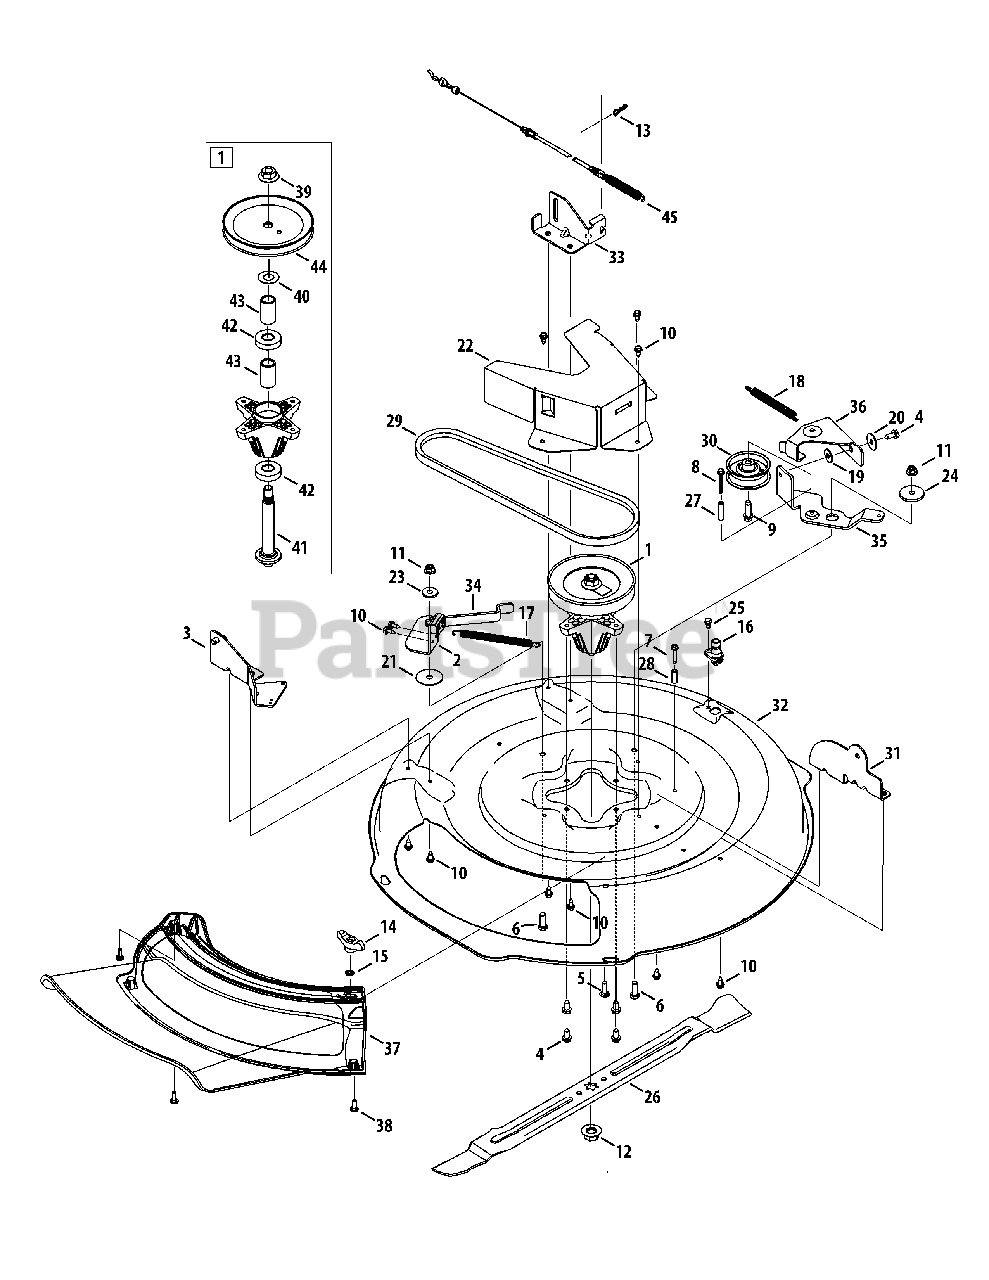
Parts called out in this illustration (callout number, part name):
1	Spindle Pulley Assembly, 6.3 DIA
2	PTO Brake Assembly Bracket
3	Rear Deck Assembly Bracket
4	Tap Screw, 5/16-18x.750
5	Carriage Screw, 5/16-18x1.00
6	Hex Head Screw, 3/8-16x1.00
7	Tap Screw, 1/4-20x1.500
8	Tap Screw, 1/4-20x1.750
9	Tap Screw, 3/8-16x1.250
10	Tap Screw, 1/4-20 X .625
11	Flange Lock Nut, 3/8-16
12	Flange Nut, 5/8-18
13	Bow-Tie Cotter Pin
14	Wing Knob, 5/16-18
15	Speed Nut, .3125 ID
16	Deck Wash Nozzle
17	Ext. Spring, .708 X 7.357 X .094
18	Ext. Spring, .56 OD X 5.52 LG
19	Shoulder Bushing, .320 ID X .135
20	Flat Washer, .330x1.250x.060
21	Thrust Washer, .445X.1.920X.060
22	Deck Belt Cover
23	Shoulder Spacer, .625 ID X .169
24	Shoulder Spacer, .8840 X .190
25	Shoulder Spacer, 1/4-20, 0.50
26	Cutting Blade, 30.00" 3-IN-1
27	Spacer, .260 X .372 X 1.420 LG
28	Spacer, .260 x .375 x 1.030 LG
29	V-Type Belt, 5L, 45.15 LG
30	Flat Idler Pulley, 2.75 OD
31	Front Deck Bracket
32	Deck, 30" w/ Nozzle
33	RR Deck Bracket, LH
34	Release Brake Bracket
35	Lower Floating Idler Bracket
36	Upper Floating Idler Bracket
37	Chute Deflector
38	Shoulder Screw, 1/4-15 x .750
39	Flange Nut, 5/8-18
40	Shim Washer, .760X1.500X.030
41	Spindle Shaft, 6.11 LG.
42	Ball Bearing, .787ID X 1.85 ODX.551
43	Spacer, .792 X 1.060 X 1.860 LG
44	Deck Pulley, 6.3 DIA
45	PTO Cable
